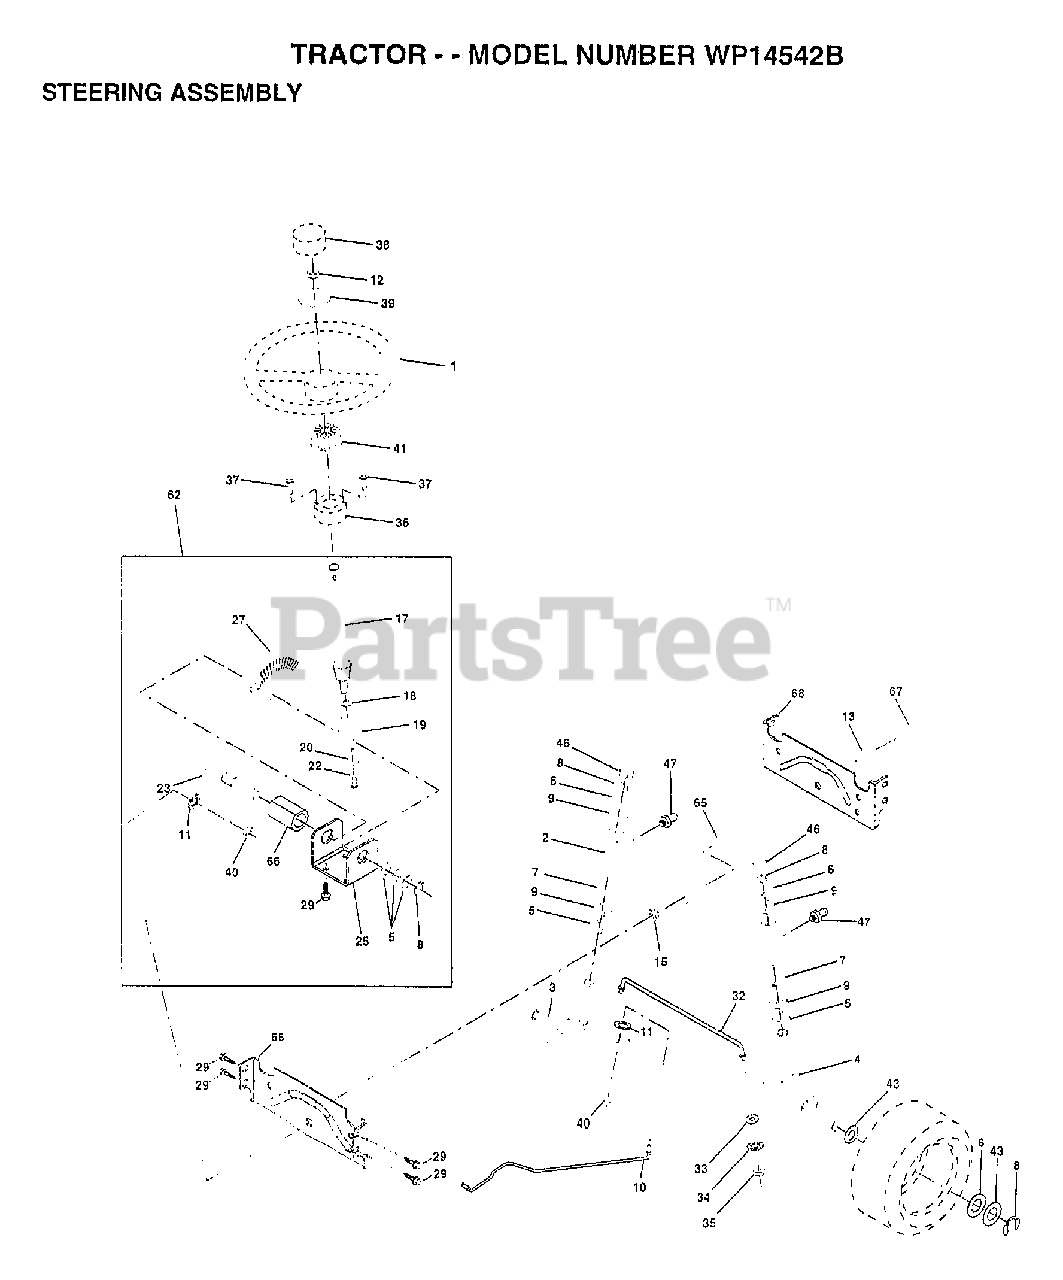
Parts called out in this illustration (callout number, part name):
2	AXLE ASM
5	WASHER .T
6	WASHER
7	WASHER
8	RING
9	COL. SRTG. BEAR.
10	DRAGLINK-STAMPED
11	LOCKWASHER
13	BEARING AXLE
15	"NUT-LOC,FLANGE LT"
17	SHAFT ASM STEERNG
18	THRUST WASHER
19	SUPPORT.SHAFT
22	SCREW HEX SOC1/4-
25	BRKT-STEERING
27	GEAR SECTOR
29	SCREW
32	ROD.TIE.19.75
33	WASHER M
34	LOCKWASHER
35	NUT.LOCK.5/16-24
36	BUSHING.STRG.3/4
37	"SCREW-TT,10-32 FL"
38	"INSERT,STR WHEEL"
39	WASHER
40	GRIPCO NUT
41	ADAPTER LT
43	WASHER
46	CAP
47	ZERK M
62	KIT STEERING ASM
65	SPACER AXLE
66	"BEARING-ARM,PITMA"
67	BOLT
68	BRACE AXLE
